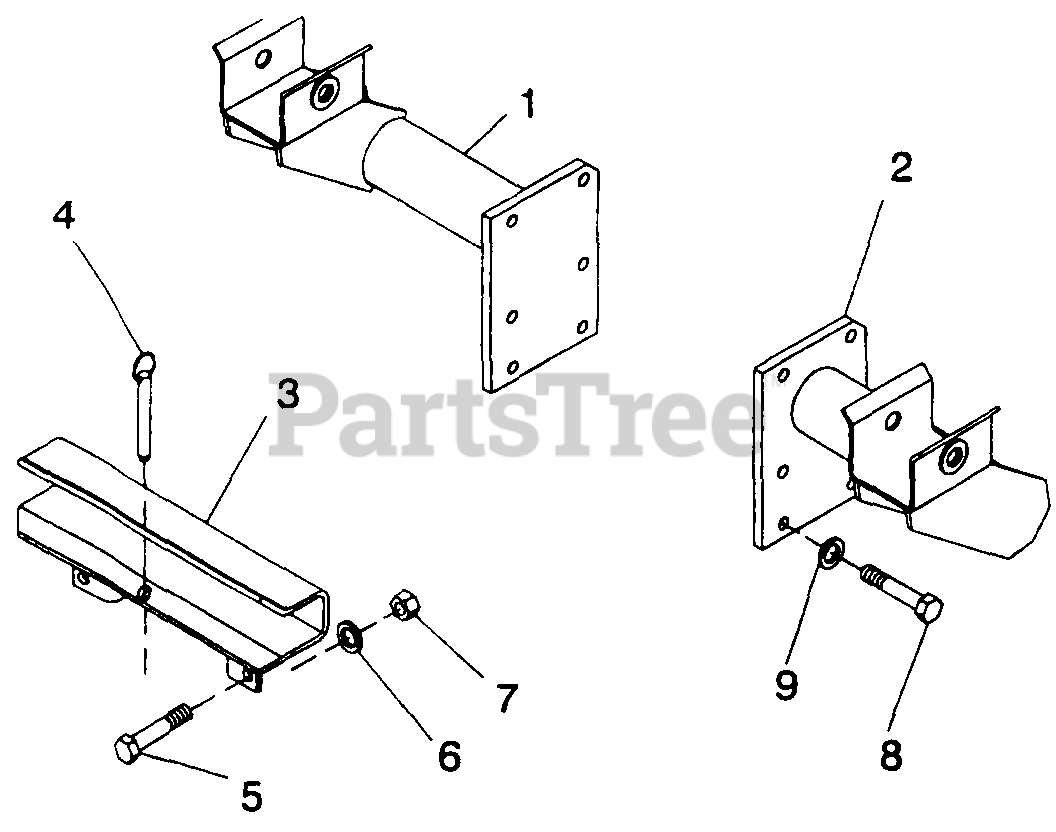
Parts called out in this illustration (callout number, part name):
1	Rear Mount, Right Side
2	Rear Mount, Left Hand
3	Front Mount
5	1/2" NC x 1-1/4 Hex head cap screw GR5
6	1/2" Lockwasher
7	1/2 NC Nut
8	M14 x 2.0 x 40mm Hex head cap screw GR8.8
9	9/16" Lockwasher
